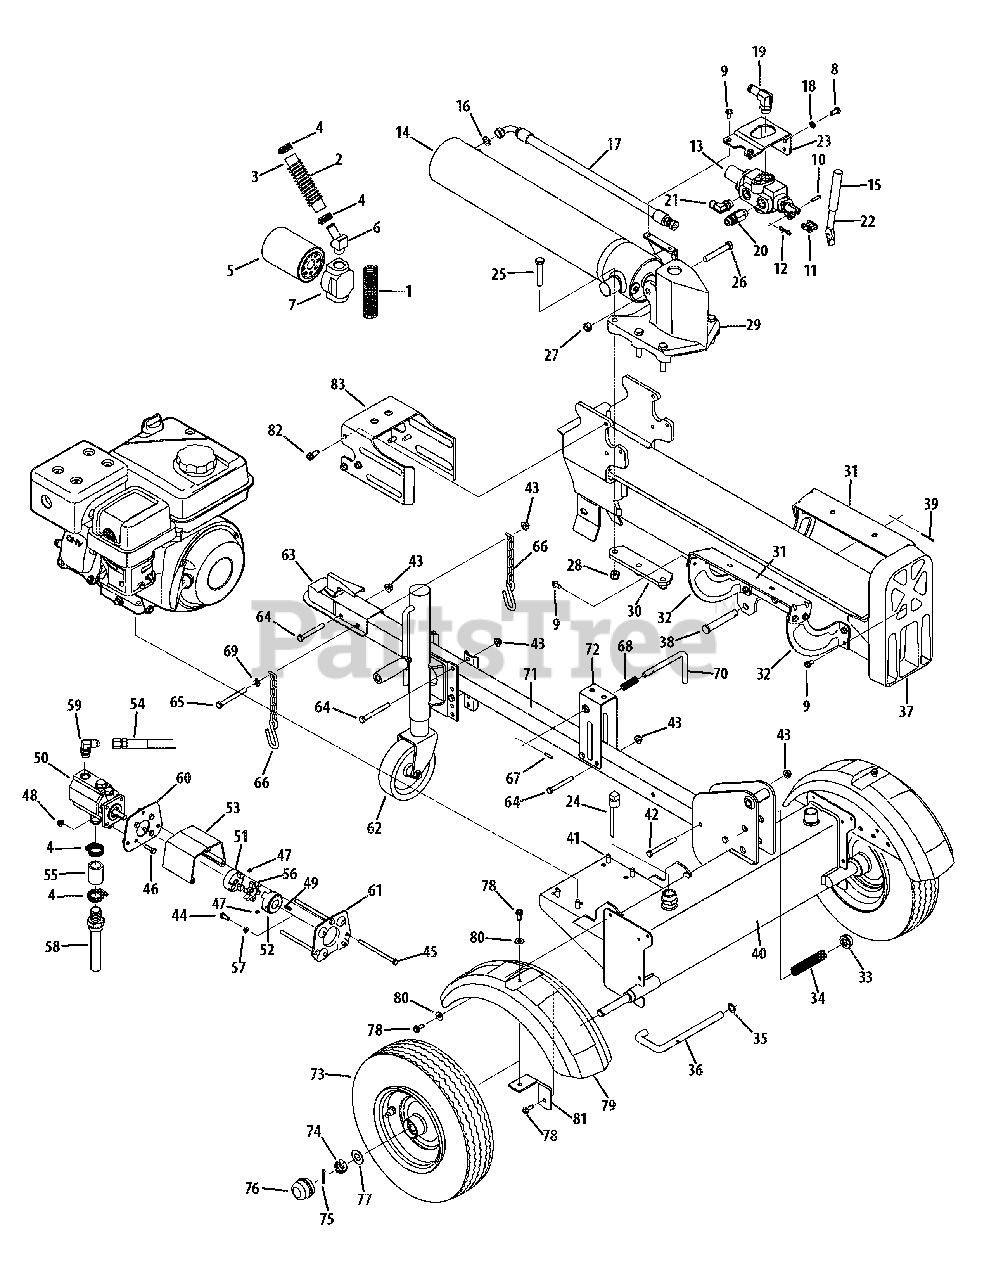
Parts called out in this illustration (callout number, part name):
1	Hose Guard
2	Hose Guard
3	Return Hose
4	Hose Clamp
5	Oil Filter
6	Hydraulic Fitting
7	Filter Housing
8	Hex Screw, 3/8-16 x .75
9	Hex Washer Screw, 5/16-18 x .750
10	Clevis Pin, .25 x 1.00
11	Valve Handle Link
12	Cotter Pin
13	Log Splitter Valve
14	Hydraulic Cylinder, 4.5 x 24
15	Grip, .625
16	Hydraulic O-Ring
17	Hydraulic Hose
18	Lock Washer, 3/8
19	Hydraulic Fitting, 7/8 x .75
20	Hydraulic Fitting, 3/4
21	Hydraulic Fitting, 3/4 x 13/16
22	Hydraulic Valve Control
23	Valve Bracket
24	Plug w/ Dipstick
25	Hex Screw, 1/2-20 x 2.75
26	Hex Screw, 1/2-13 x 3.25
27	Hex Lock Nut, 1/2-13
28	Hex Lock Nut, 1/2-20
29	Log Splitter Wedge
30	Log Splitter Wedge Plate
31	Log Tray Bracket
32	Log Splitter Tray Bracket
33	Push Cap, 5/8
34	Compression Spring, .625 x 4.0
35	Flat Washer, .635 x .930 x .060
36	Beam Lock Rod
37	Beam Assembly
38	Clevis Pin, .625 x 4.25
39	Cotter Pin, 1/8 x 1.25
40	Tank Assembly
41	Hex Washer Screw, 3/8-16 x 1.000
42	Hex Screw, 3/8-16 x 3.50
43	Flange Lock Nut, 3/8-16
44	Hex Screw, 5/16-24 x .75
45	Hex Screw, 5/16-18 x 4.00
46	Hex Screw, 5/16-18 x 1.00
47	Set Screw, 1/4-20 x .38
48	Flange Lock Nut, 5/16-18
49	Square Key, 3/16 x .75
50	Gear Pump
51	Coupling, .500
52	Coupling, .750
53	Coupling Shield Spacer
54	Hydraulic Hose
55	Input Hose, 1.0
56	Spider Bushing
57	Lock Washer, 5/16
58	Inlet Filter
59	Hydraulic Fitting
60	Rear Coupling Support Bracket
61	Front Coupling Support Bracket
62	Adjustable Stand Assembly
63	Hitch Coupling Assembly
64	Hex Screw, 3/8-16 x 3.00
65	Hex Screw, 3/8-16 x 3.50
66	Tow Chain
67	Spirol Pin, 3/16 x 1.00
68	Compression Spring, .66 x 1.9
69	Flat Washer, .375 x .738 x .063
70	Latching Rod
71	Tongue Tube, 2.0 x 2.0
72	Tongue Latch
73	Complete Wheel, 16.0 x 4.8 x 8.0
73	Rim, 3.75 x 8.0
73	Tire, 16 x 4.80-8
73	Inner Tube, 4.80/4.00-8
73	Grease Retainer
73	Bearing
74	Slotted Nut, 3/4-16
75	Cotter Pin, 5/32 x 1.25
76	Hub Cap
77	Flat Washer, .760 x 1.50 x .030
78	Hex Washer Screw, 5/16-18 x 1.000
79	Fender
80	Thrust Washer, .343 x .880 x .062
81	Fender Mount Bracket
82	Hex Washer Screw, 3/8-16 x 1.000
83	Dislodger Bracket
